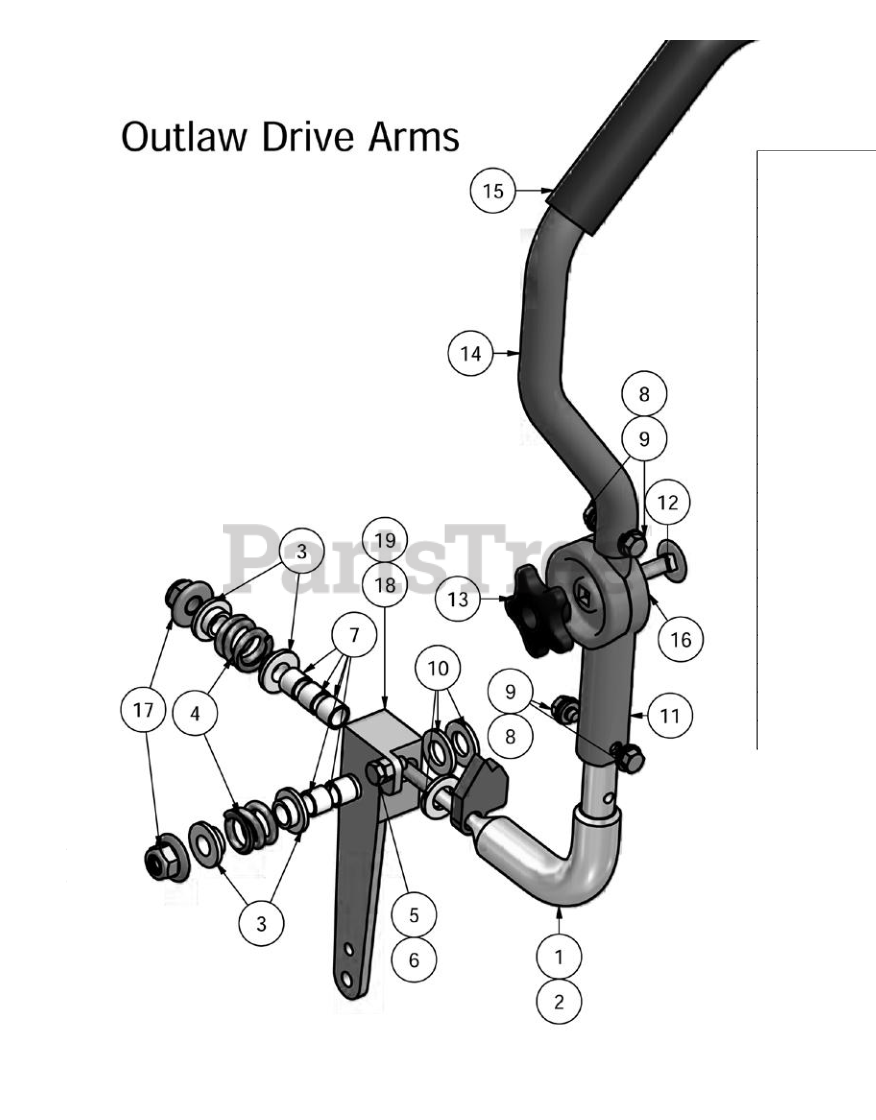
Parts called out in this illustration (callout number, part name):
1	Steering Arm Base-Right
2	Steering Arm Base-Left
3	.515 ID Nylon Shoulder Washer
4	Drive Lever Spring
5	5/16" x 3/4" Hex Bolt
7	.507 ID Nylon Bushing
8	5/16" Lock Washer
9	5/16" x 1/2" Flange Bolt
10	.635 ID Plastic Washer
11	Upper Adjuster for Steering Arm
12	3/8" x 1-1/4" Carriage Bolt
13	Black Knob for Adjustable Steering Arm
14	Upper Steering Arm Tubing-Adjustable
15	Rubber Grip
16	Lower Adjuster for Steering Arm
17	1/2-13 Nylon Flange Nut-Orange
18	Drive Arm Lever Housing-Left
19	Drive Arm Lever Housing-Right
